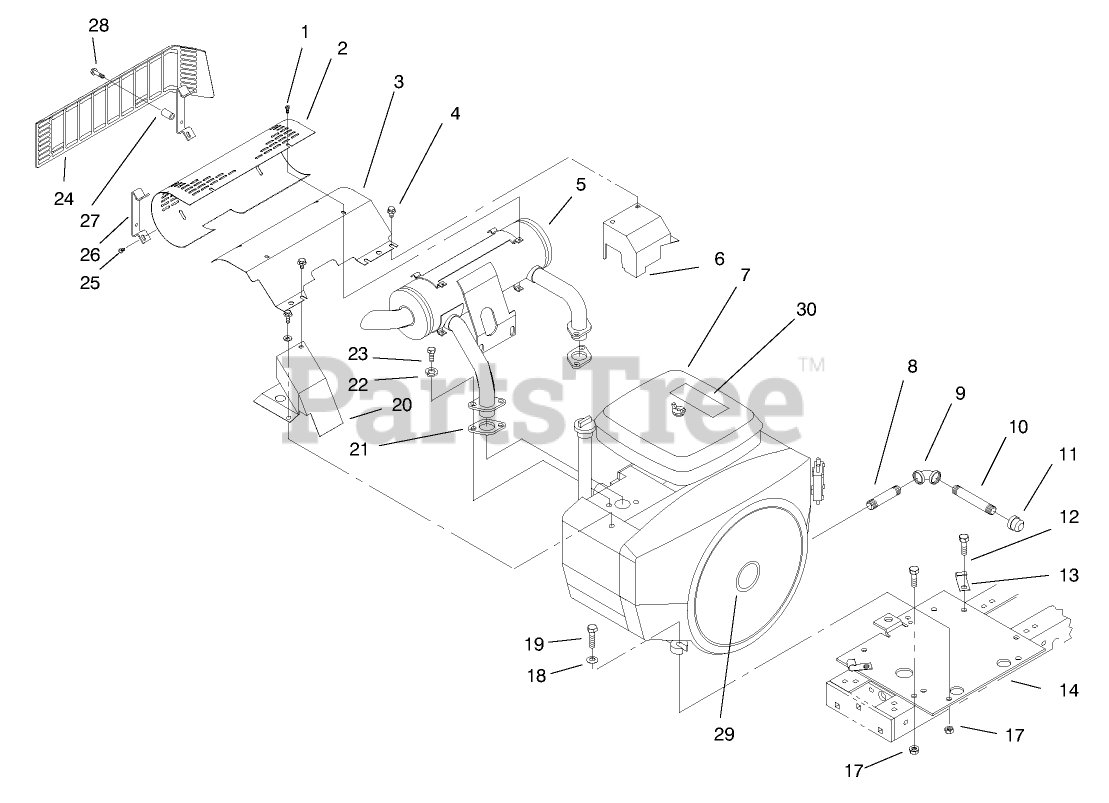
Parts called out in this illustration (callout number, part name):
4	SCREW-HWHTF
5	MUFFLER-EXHAUST
9	ELBOW 3/8 90 DEG
10	PIPE-NIPPLE 3/8 X 4"
11	CAP-PIPE
12	SCREW-HH
13	CLIP
17	NUT-LOCK, NI
18	WASHER-FLAT
19	SCREW-HH
21	GASKET
22	WASHER-LOCK
23	SCREW-HH
25	Screw-Phcr
26	Bar-Guard
28	SCREW-HWH
29	NAME-PLATE TORO LOGO
30	DECAL-PWR PLUS 16 PL
